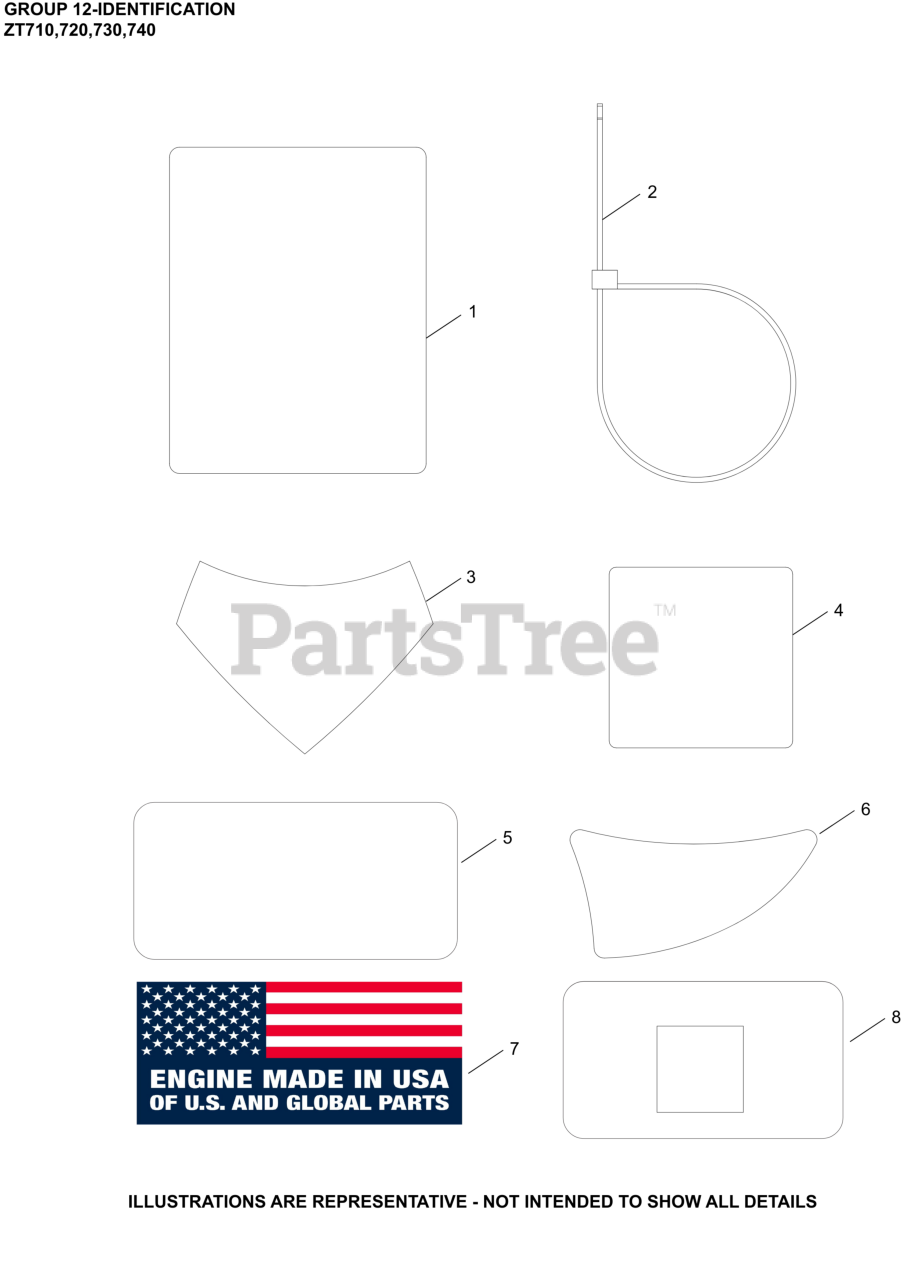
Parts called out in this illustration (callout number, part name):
1	LABEL, CLEAR LAMINATION
4	LABEL, CONFIDANT (23HP, HPAC)
7	DECAL, USA
